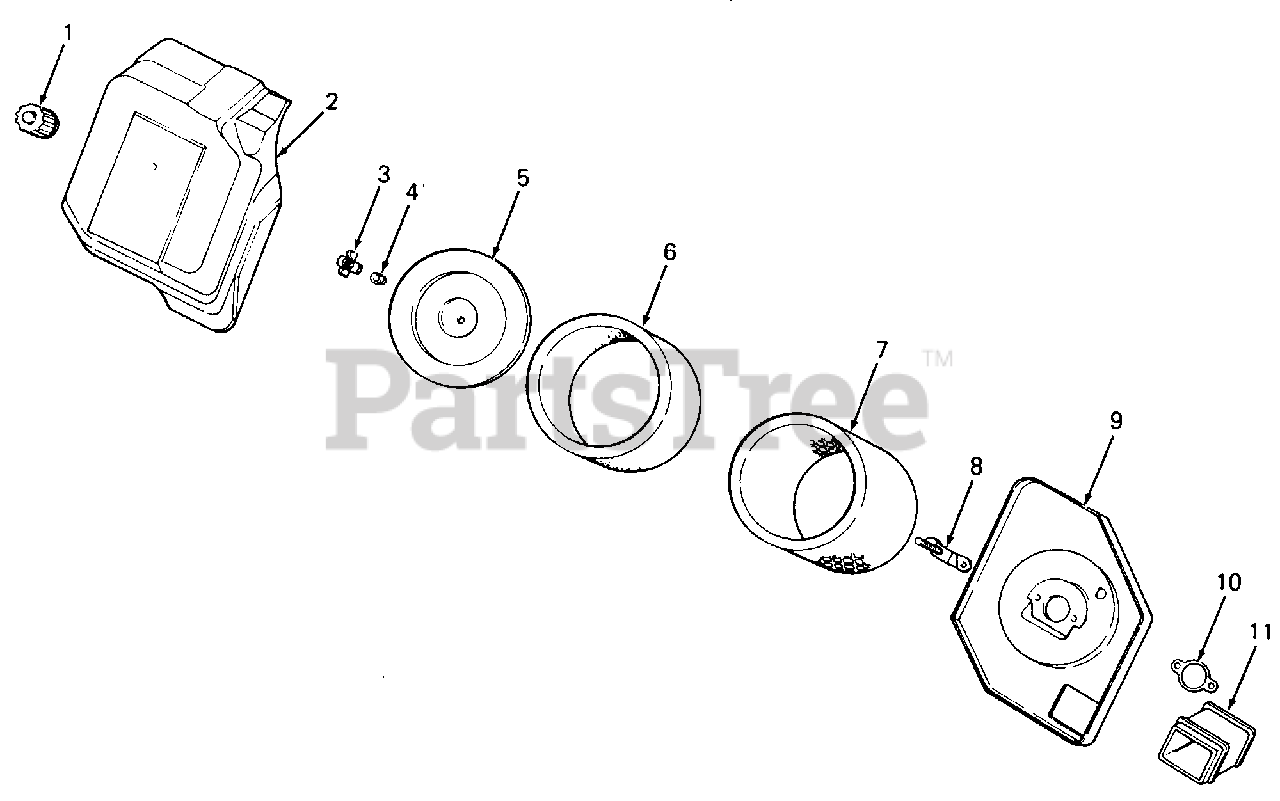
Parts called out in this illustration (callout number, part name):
1	Knob, Air Cleaner Cover
2	Cover, Air Cleaner
5	Cover, Element
6	Precleaner, Element
7	Element, Air Cleaner
8	Bracket, Air Cleaner
9	Base, Air Cleaner
10	Gasket, Air Cleaner
11	Tube, Air Intake
